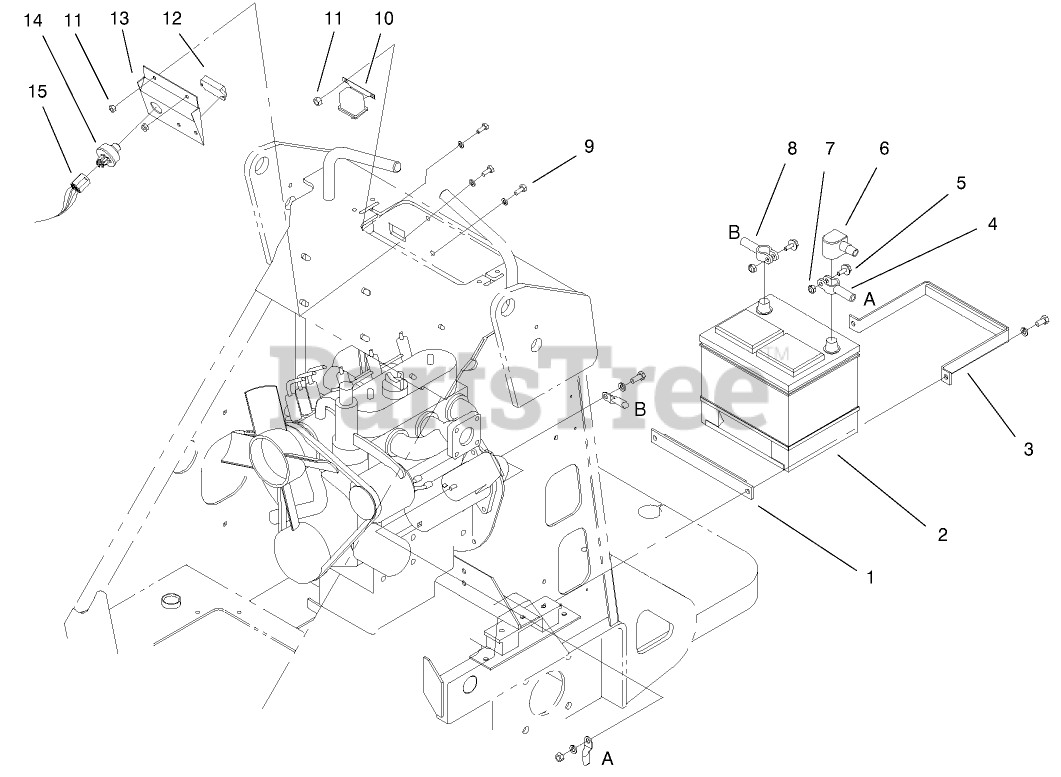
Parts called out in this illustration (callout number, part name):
1	PLATE-BATTERY MOUNT
2	Battery
3	BRACKET-BATTERY
4	CABLE-POS
5	SCREW-HHF
6	BOOT-TERMINAL, RED
7	NUT-LOCK, NI
8	CABLE-NEG
9	SCREW
10	BUZZER
11	NUT-HEX
12	Tachometer
13	Bracket
14	ASSY SWITCH, STARTER
15	HARNESS-ELECTRICAL
